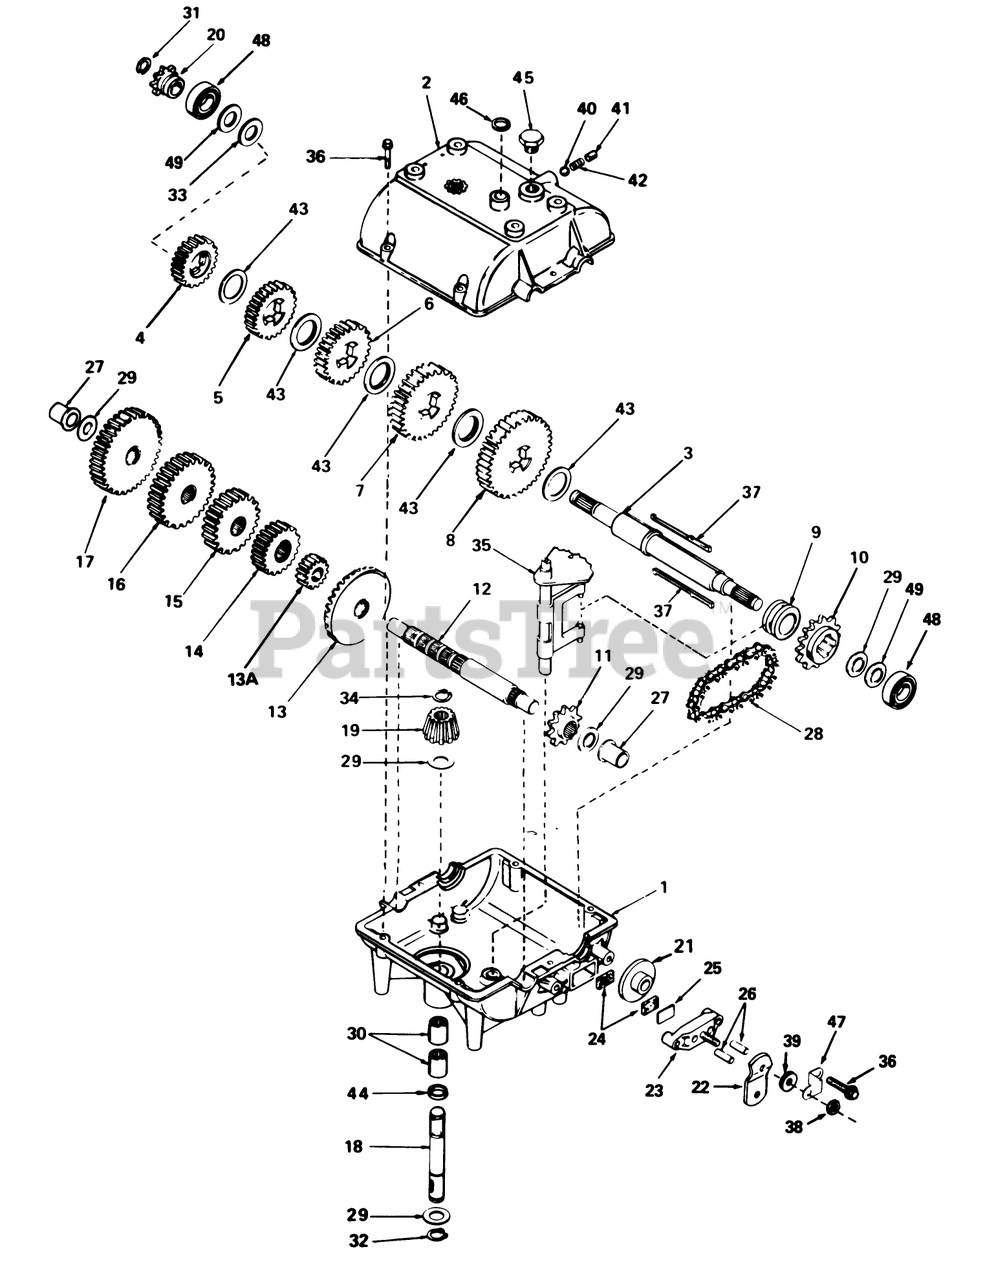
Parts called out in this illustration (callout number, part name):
1	Case-Transmission
2	Cover-Transmission
3	Shaft, Output
4	Gear, Spur (19 teeth)
5	Gear-Spur (22 teeth)
6	Gear-Spur, 25 Teeth
7	Gear-Spur, 30 Teeth
8	Gear-Spur, 35 Teeth
9	Collar-Shift
10	Sprocket-18 Teeth
11	Sprocket-9 Teeth
12	Countershaft
13	Gear-Bevel (42Teeth)
13A	Gear-Spur 15 Teeth
14	Gear-Spur, 20 Teeth
15	Gear-Spur, 25 Teeth
16	Gear-Spur (28 teeth)
17	Gear, Spur (31 Teeth)
18	Shaft-Input
19	Bevel Pinion-Input
20	Sprocket (8 teeth)
22	Lever, Brake
23	Nozzle-Carburetor
24	Brake Pad
25	Brake Pad Plate
26	Dowel Pin
27	Bushing-Flange
28	Chain-Roller #41
29	Washer
30	Bearing-Needle
31	Piston Asm (.020 O S)
32	Ring-Snap
33	Washer
34	Ring-Retainer
35	Rod and Fork ASM
36	Ring Set (.020 O S)
38	Locknut
39	Washer
40	Ball-Steel
41	Screw-Set
42	Spring
43	Washer
44	O Ring
46	Cut Seal-Square
47	Bracket
48	Bearing-Ball
49	Thrust Washer
